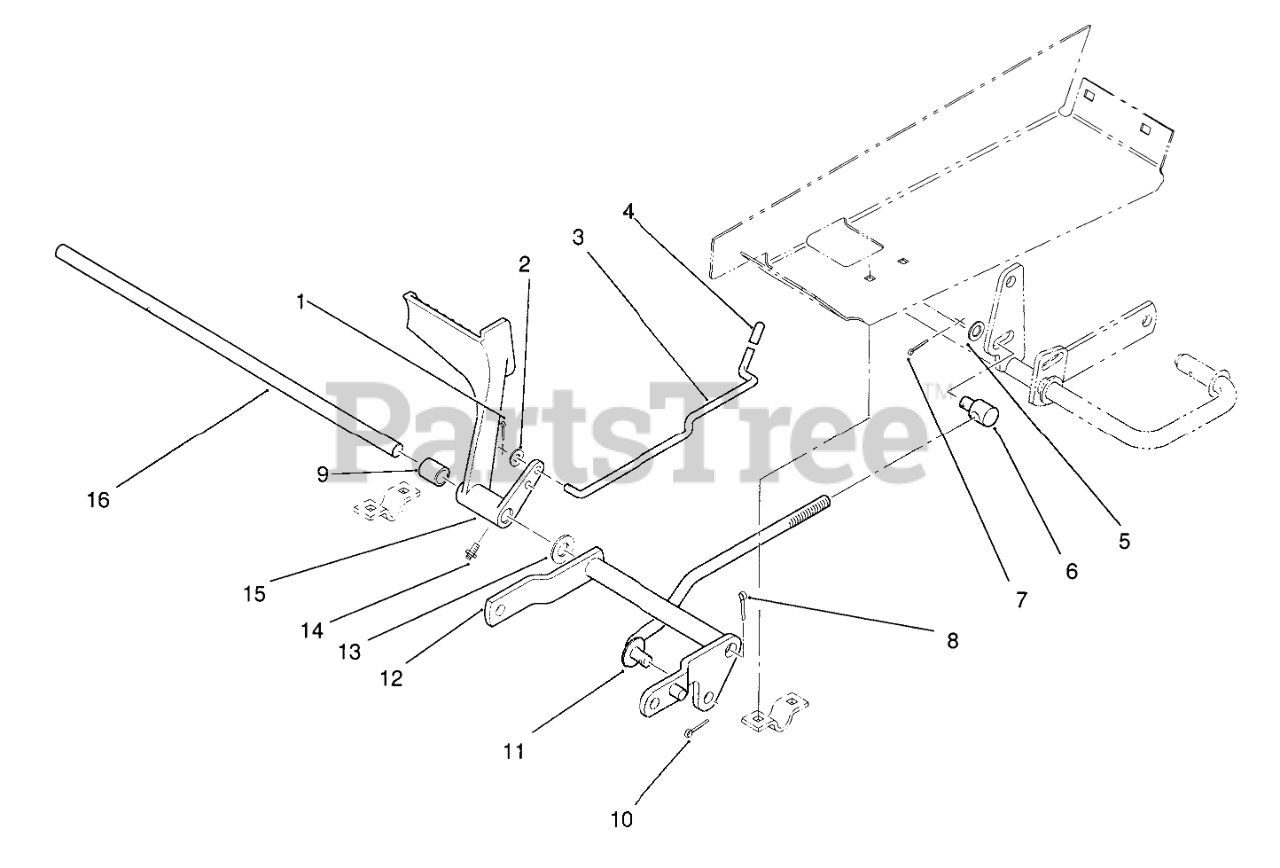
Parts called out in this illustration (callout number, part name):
1	Cotter Pin
2	WASHER 5/16 SAE
3	ROD-BRAKE LOCK
5	Washer
6	ROD-TRUNNION LIFT
7	Cotter Pin
9	SPACER
10	Cotter Pin
11	Rod-W.A.
12	Arm
13	Washer
14	Fitting-Grease
15	Pedal-Brake
16	SHAFT R
